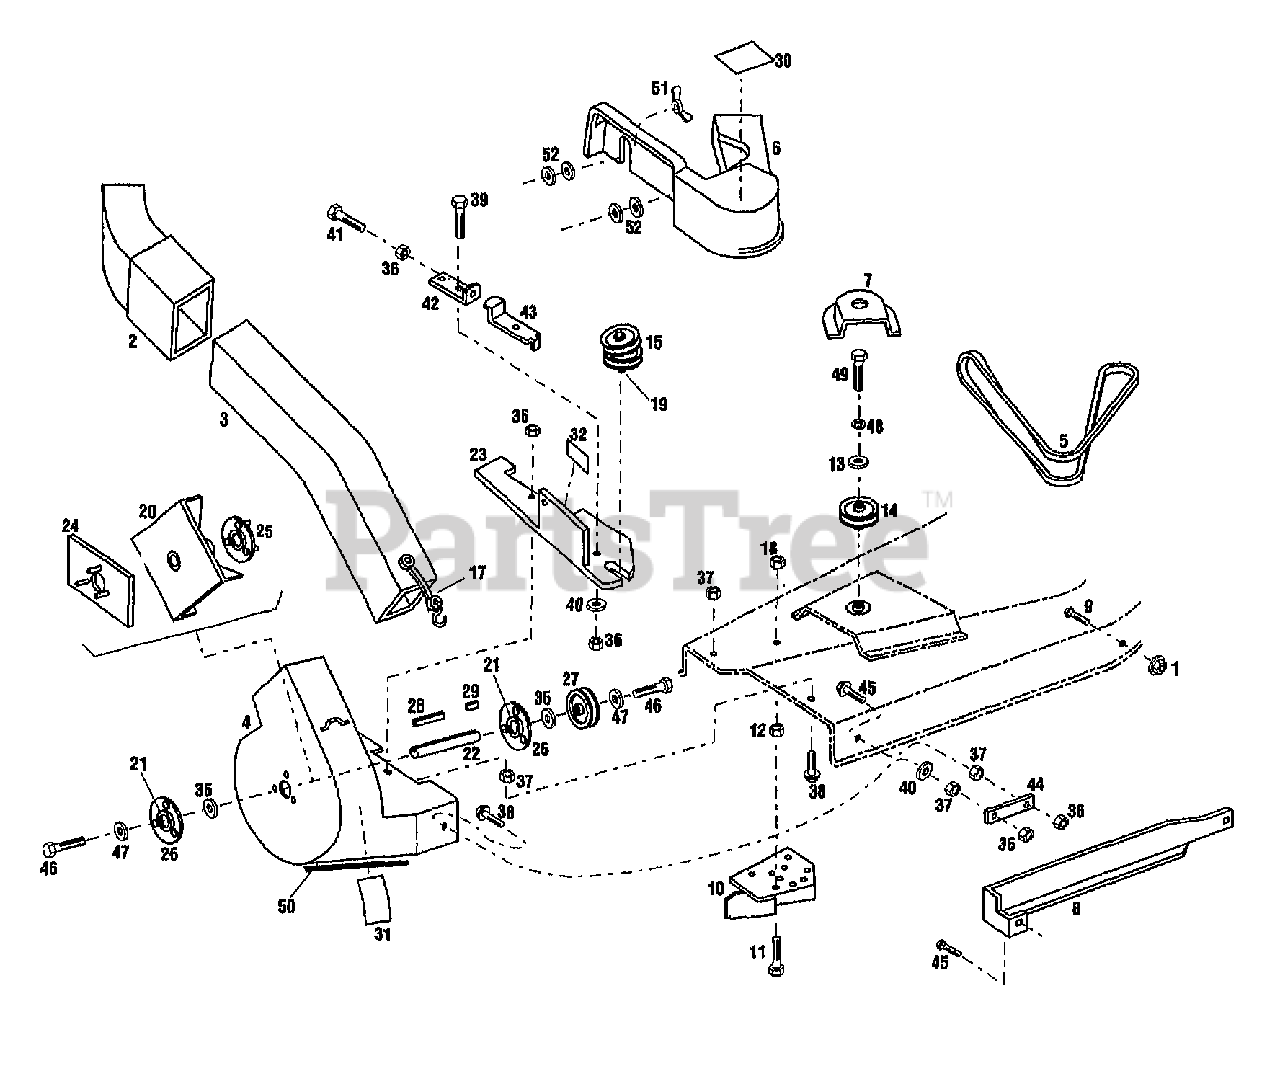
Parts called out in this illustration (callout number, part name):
1	NUT-HFLK 5/16-18 ZP
1	CHUTE-UPPER ELBOW
3	TUBE-LONG
4	HOUSING
5	BELT-V
6	GUARD-BELT
7	GUARD-BELT
8	BAFFLE-LONG
9	SCR-CARR 5/16-18X.62 G2 ZP
10	ASSM-BAFFLE
11	SCR-HH 3/8-16X1.0 G5 ZP
12	NUT-HEX JAM 5/16-18
13	WASHER-1.25X.5X.083 ZP
14	SHEAVE
15	SHEAVE-DOUBLE IDLER
17	ASSM-STRAP
18	NUT-LOCK 3/8-16
19	SHAFT-DOUBLE IDLER
20	IMPELLER
22	SHAFT-FAN 3/4"
23	FRAME-MOUNTING
24	FLANGETTE-OUTER
25	FLANGETTE-INNER
27	SHEAVE-FAN
28	KEY-.188 SQ X 2.0
29	KEY-.187 SQ X .75
30	DECAL-DANGER
31	DECAL-DANGER
32	DECAL (MT FRAME)
35	WASHER-THRUST
36	NUT-H/LK 5/16-18
37	NUT-HEX JAM 5/16-18
38	SCR-HFLK 5/16-18X1.00 ZP
39	SCR-HH 5/16-18X.875 G5 ZP
40	WASHER-FLAT 5/16 SAE
41	SCR-HH 5/16-18X2.75
42	ASSM-BRKT
43	BRKT-ADJUSTMENT
44	SUPPORT
45	SCR-CARR 5/16-18X1.0 G2 ZP
46	SCR-HHC 5/16-18X.75 GR 5 ZP
47	WASHER-1.25X.343X.059
48	WASHER-LK .438 ZP
49	SCR-HH 7/16-14X2.00
50	STRIP-WEAR
51	NUT-WING
52	WASHER-.75X.312X.065 ZP
